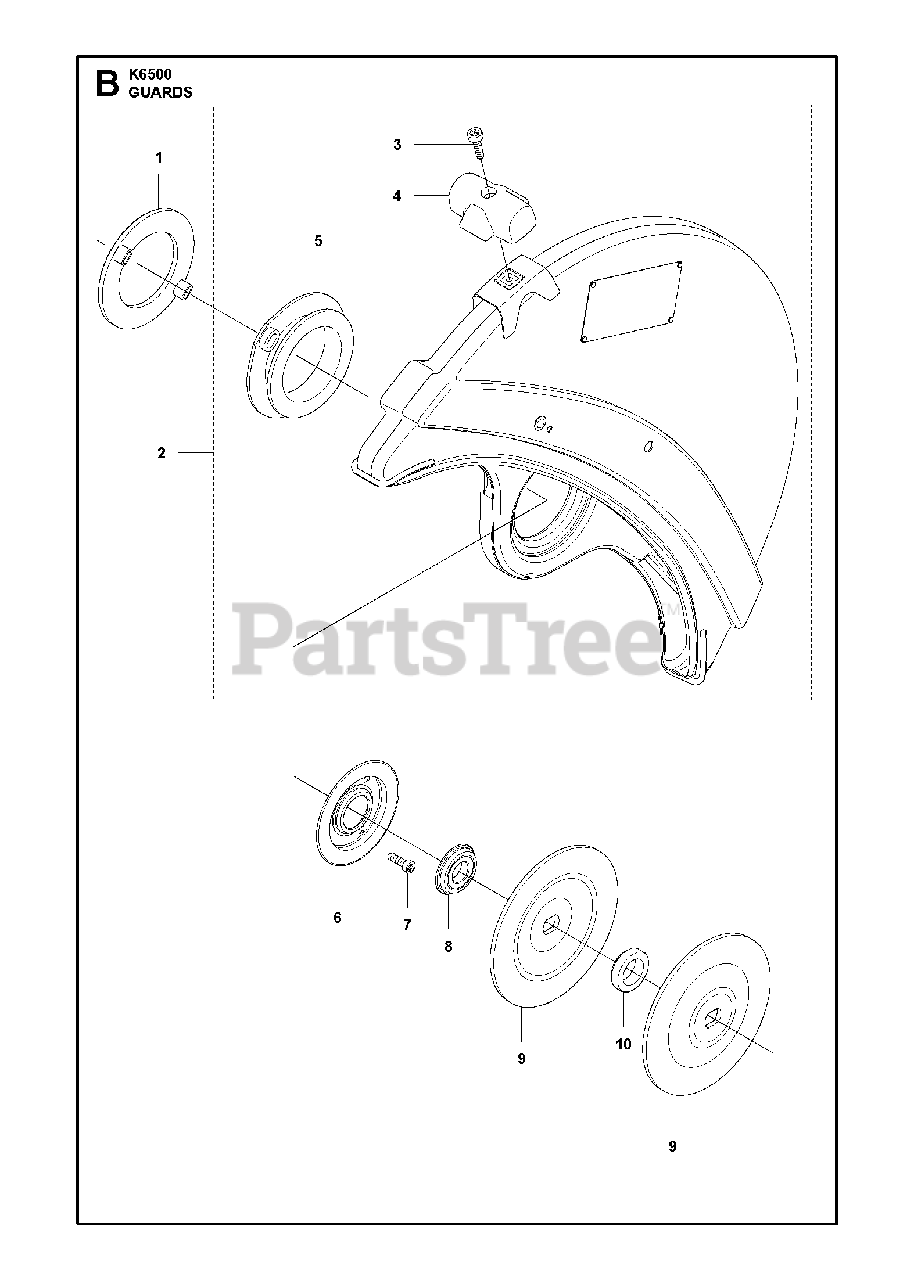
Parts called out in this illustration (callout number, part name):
2	BLADE GUARDIncl. 3-5
3	SCREW ITXSCM
7	SCREW ITXSCM
8	SUPPORT FLANGE
9	FLANGE WASHERDiam 105
9	FLANGE WASHERDiam 119
10	KITDiam 25,4
10	BUSHINGDiam 30,5
